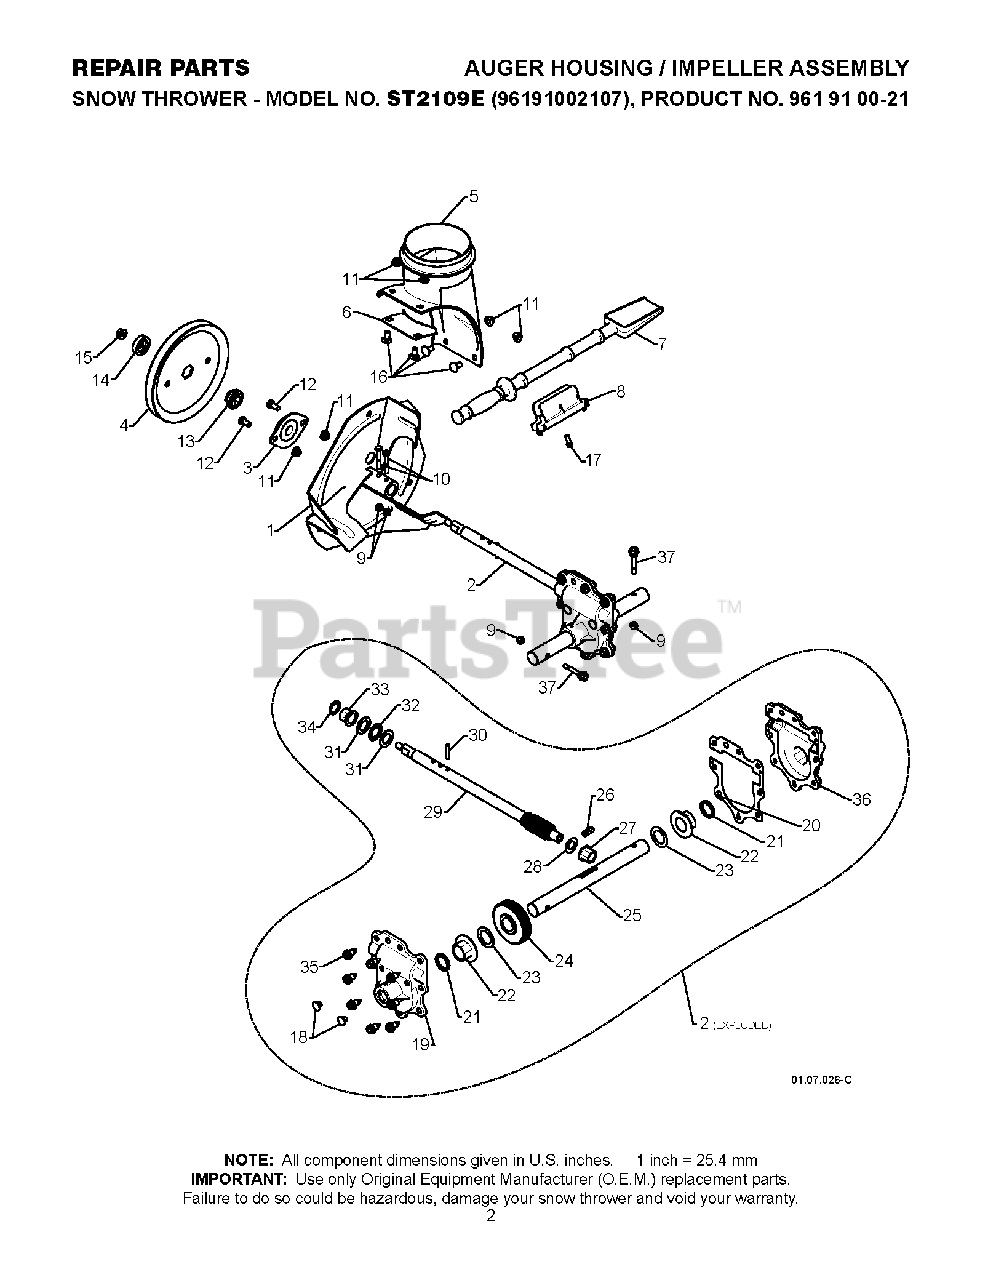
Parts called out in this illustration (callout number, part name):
1	IMPELLER ASSY
2	GEARBOX.ASM.AUGER.D-SHAFT
3	BEARING FLANGE
4	PULLEY.FLANGE.IMPELLER
5	BASE DISCHARGE CHUTE
6	BRACKET, CORNER DISCHARGE
7	CLEAN OUT TOOL
8	CLIP.CLEANOUT.TOOL
9	LOCKNUT
10	SCREW.HEX.HD1/4-20X
11	NUTNYLOK.FLRANGE.5/16-18
12	BOLT, HEX HEAD 5/16-18
13	HUB.IMP.PULLEY.D-SHAFT
14	SLEEVE.IMP.PULLEY.D-SHAFT
15	NUT LOCK FLG 3/8-16 UNC
16	BOLT.CARRIAGE.5/16-18X
17	SCREW.HWH.13-16-5.8.BZP
18	CASE PLUG
19	GEAR.BOX.COVER.RIGHT.SIDE
20	GASKET.GEAR.BOX
21	OIL SEAL
22	FLANGE BUSHING-1"
23	WASHER TRUST 1"
24	WORM GEAR
25	AUGER SHAFT
26	KEY, SQUARE 1/4 X .875
27	FLANGE BUSHING-5/8
28	WASHER, THRUST 5/8
29	SHAFT.IMPELLER.D-SHAFT
30	PIN, ROLL 3/16 X 1-1/8
31	WASHER, THRUST 3/4
32	BEARING TRUST 3/4
33	BUSHING, FLANGE 3/4
35	HEX SCREW-5/16 X 3/4
36	GEAR.BOX.COVER.LEFT.SIDE
37	BOLT, SHOULDER SHEAR
